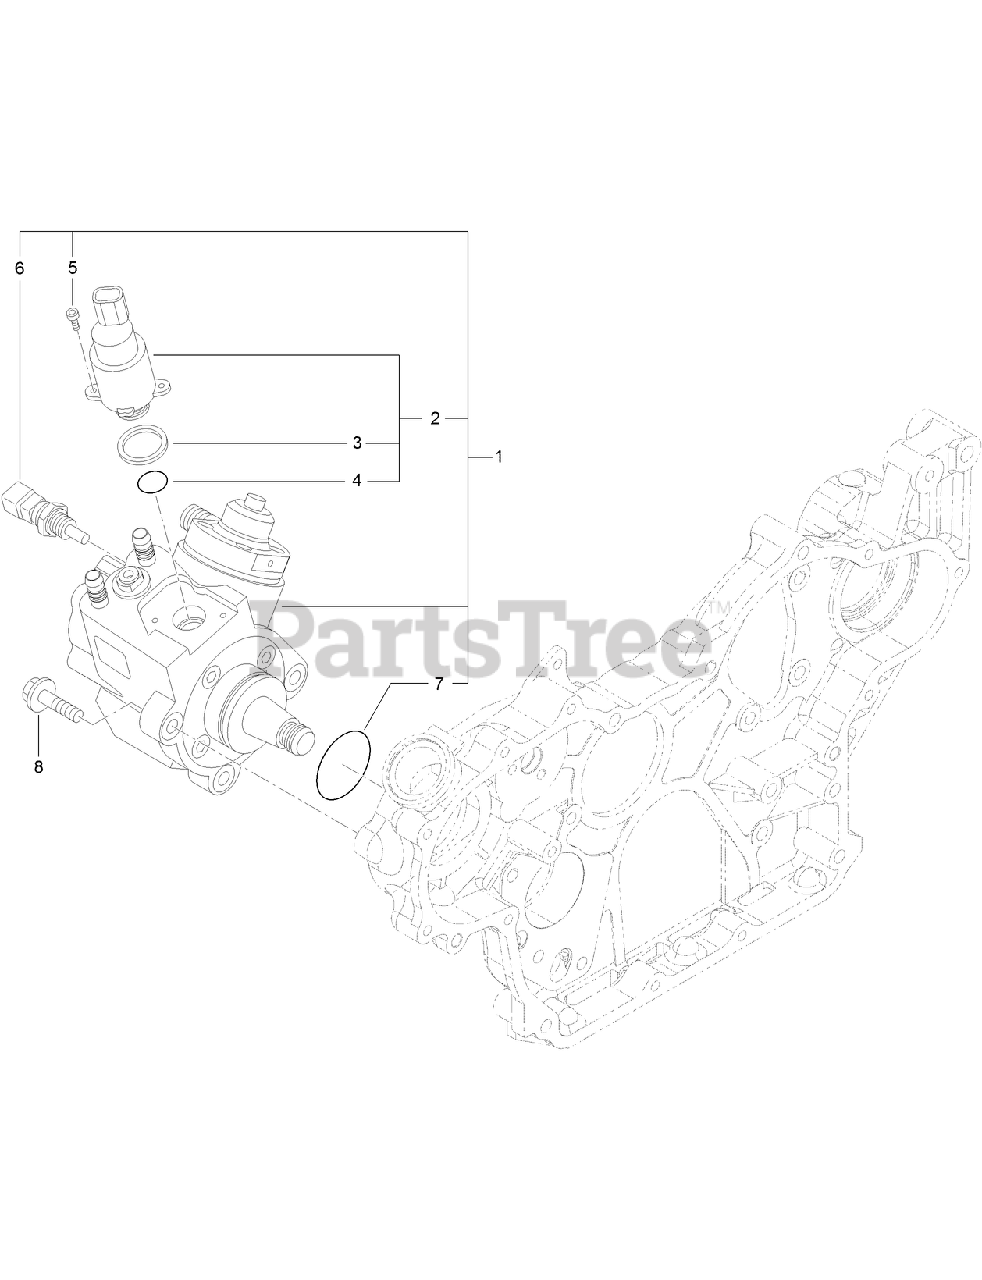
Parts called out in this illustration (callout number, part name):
1	FUEL PUMP ASM
2	VALVE ASM
3	RING-SEALING
4	O-RING
6	SENSOR-TEMPERATURE
7	O-RING
